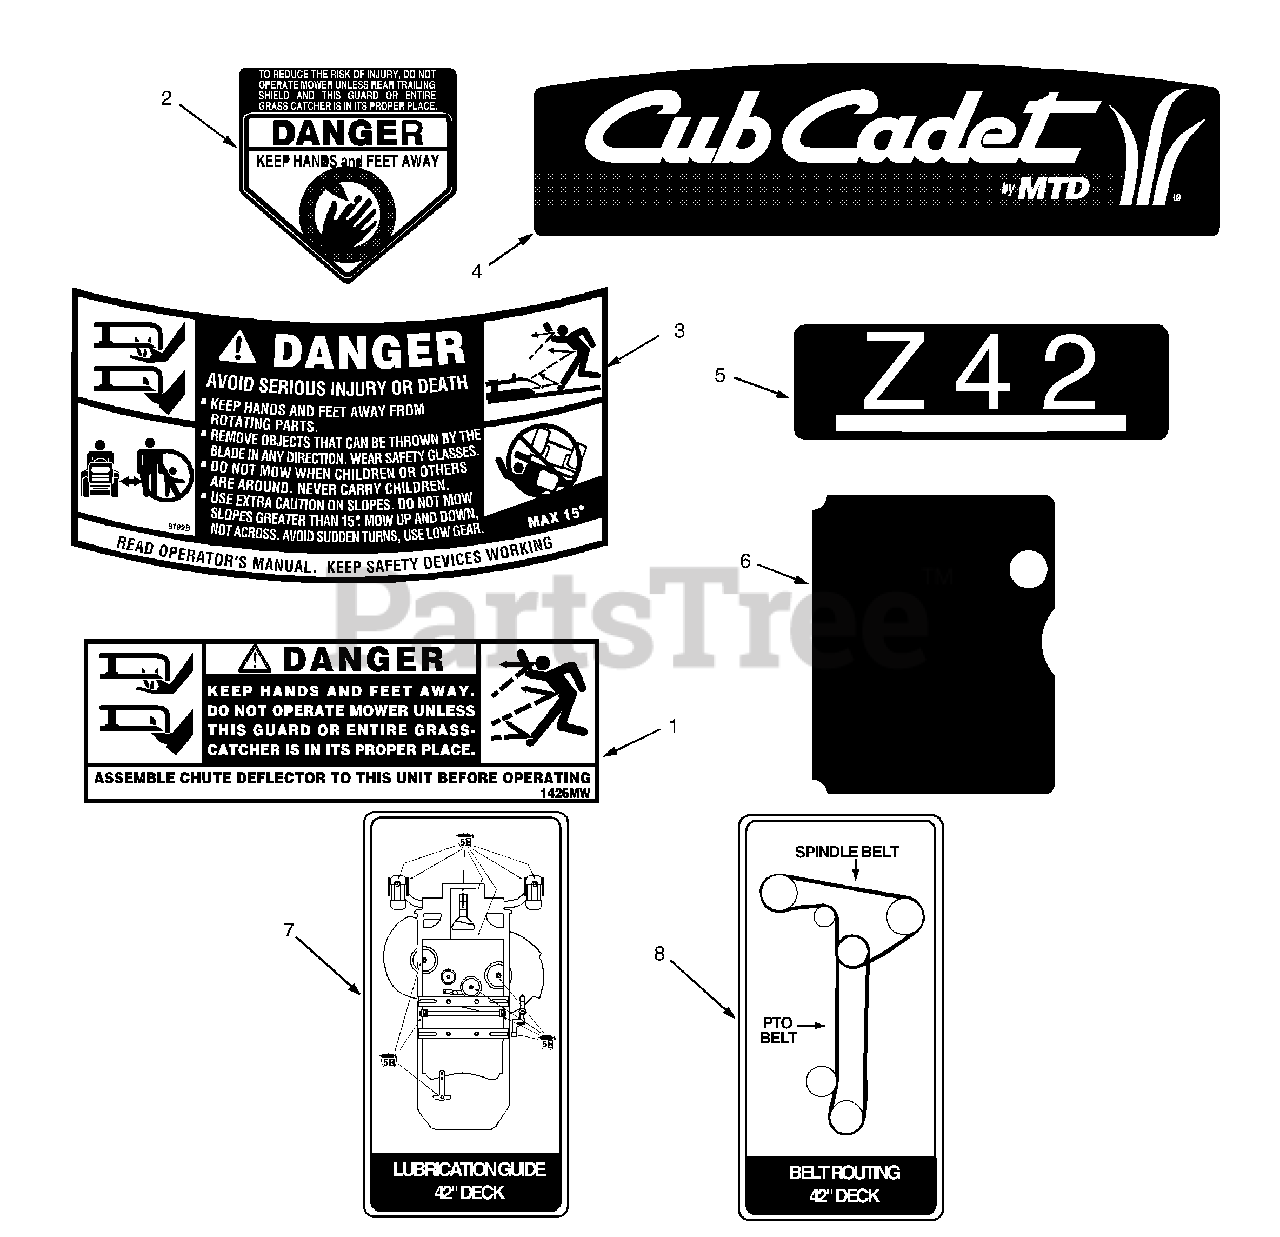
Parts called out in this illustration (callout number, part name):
1	Label, Danger - Top of Deck
2	Label, Danger - Top of Deflector Chute
3	Label, Safety - Top of Deck
4	Label, Model - Back of Seat
5	Label, Model - Front Steering Console
6	Label, Control Panel Cover- Hr/Tach
7	Label, Information - Under Belt Cover
8	Label, Information - Under Belt Cover
